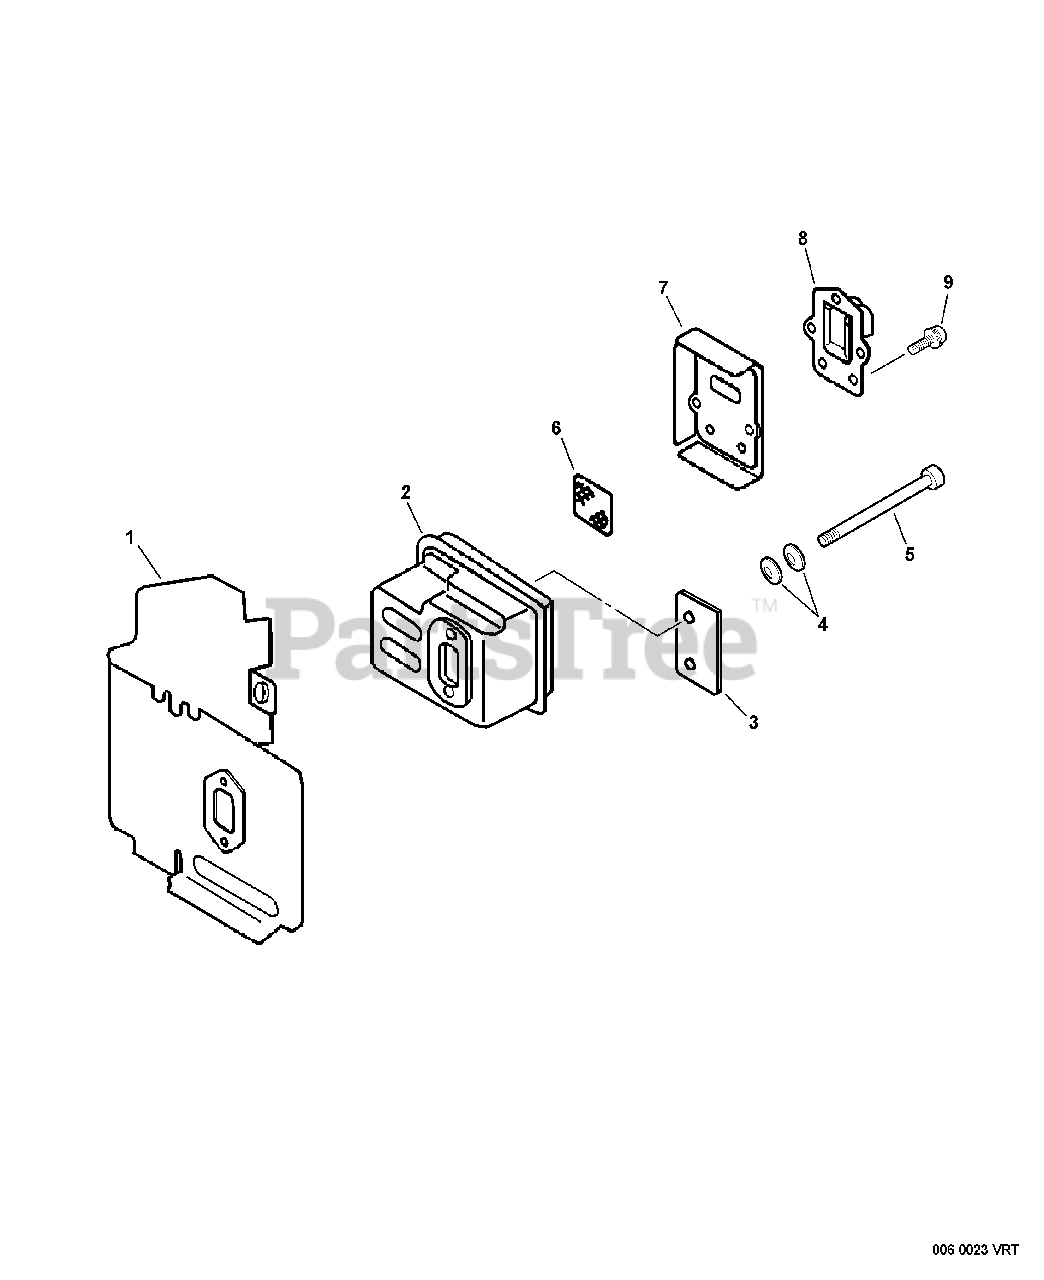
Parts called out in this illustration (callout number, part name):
1	SHIELD, EXHAUST
2	MUFFLER
4	WASHER - CONICAL
5	SCREW - 5X55
6	SCREEN, SPARK ARRESTOR
7	GASKET, EXHAUST
8	GUIDE, EXHAUST
9	SCREW - 4X12
